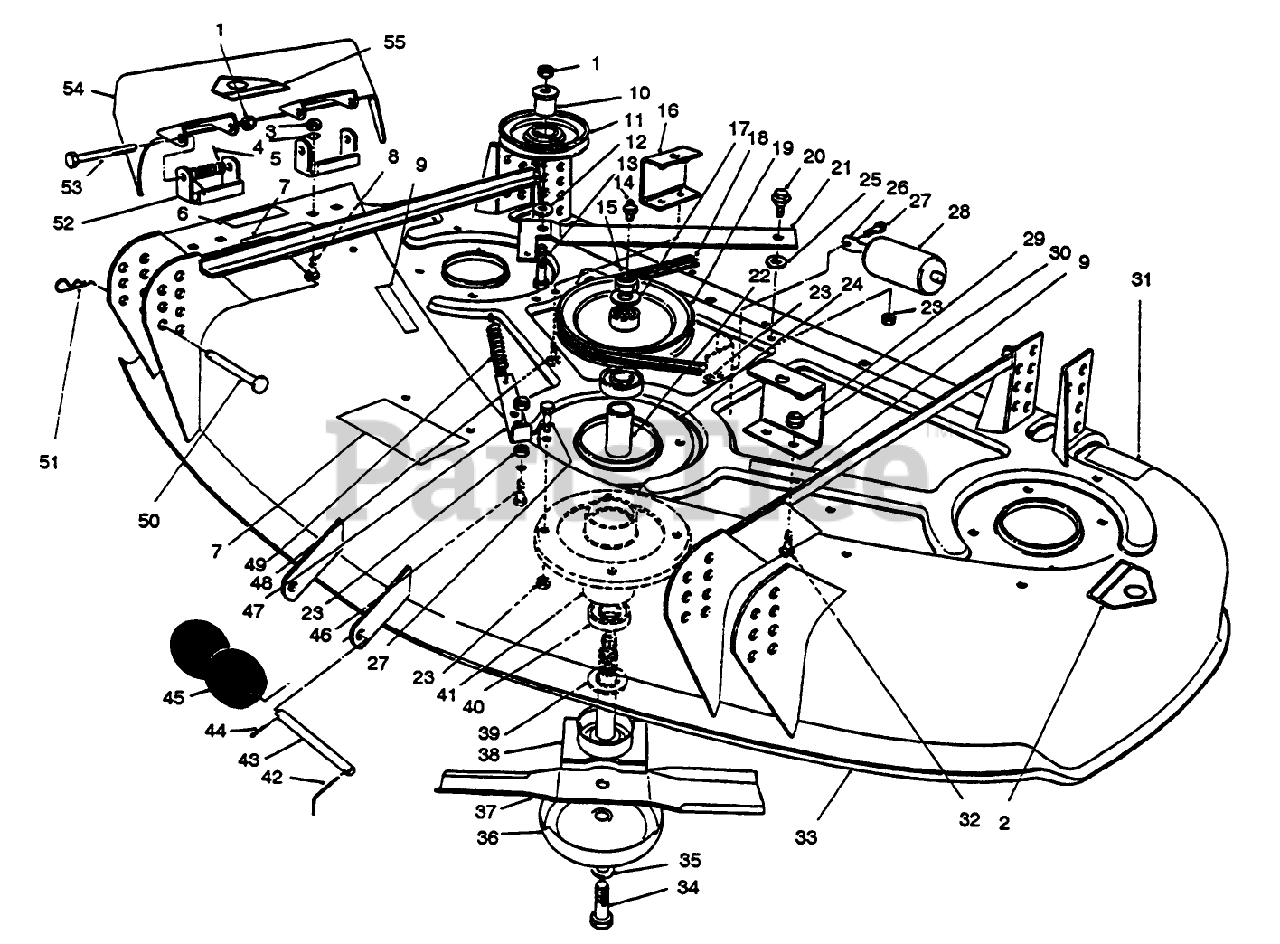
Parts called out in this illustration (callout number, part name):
1	NUT-HEX
2	DECAL-DANGER
3	NUT-HEX
4	SCREW-HH
5	SPRING
6	DECAL-DANGER
7	DECAL-DANGER, THROWN OBJECT
9	DECAL-DANGER
10	BUSHING-PULLEY
11	PULLEY-IDLER
12	WASHER-FLAT
13	SCREW-HH
14	FITTING-GREASE
15	NUT-HEX
17	WASHER
18	V-BELT-DECK
19	PULLEY-DECK
20	SCREW-SHOULDER
22	SPACER-BEARING
23	NUT-LOCK, CONE
25	WASHER
26	ROD-ROLLER
27	SCREW-HH
28	ROLLER-DECK
29	NUT-LOCK, NI
31	DECAL-TORQUE
32	SCREW-CARR
34	SCREW-BLADE
35	WASHER-LOCK
36	CUP-SCALP, ANTI
39	SPACER-SPINDLE
40	BEARING-BALL
41	HOUSING-SPINDLE
42	PIN-SPECIAL
43	SHAFT-ROLLER
44	PIN-COTTER
45	ROLLER
46	SCREW-HH
48	SCREW-CARR
49	SPRING-EXTENSION, DECK
50	PIN-CLEVIS
51	PIN-HAIR
53	SCREW-HH
54	DEFLECTOR
